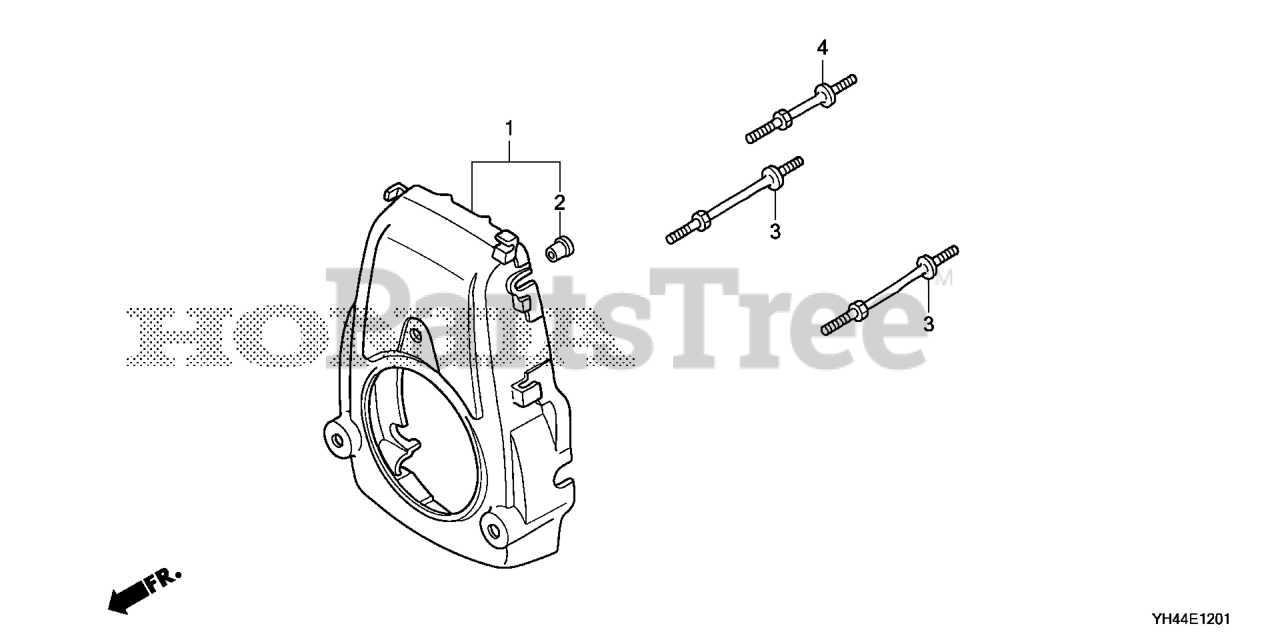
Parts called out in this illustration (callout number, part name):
1	COVER, FAN *R280* (POWER RED)
2	COLLAR, FAN COVER
3	BOLT A, STUD
4	BOLT B, STUD
